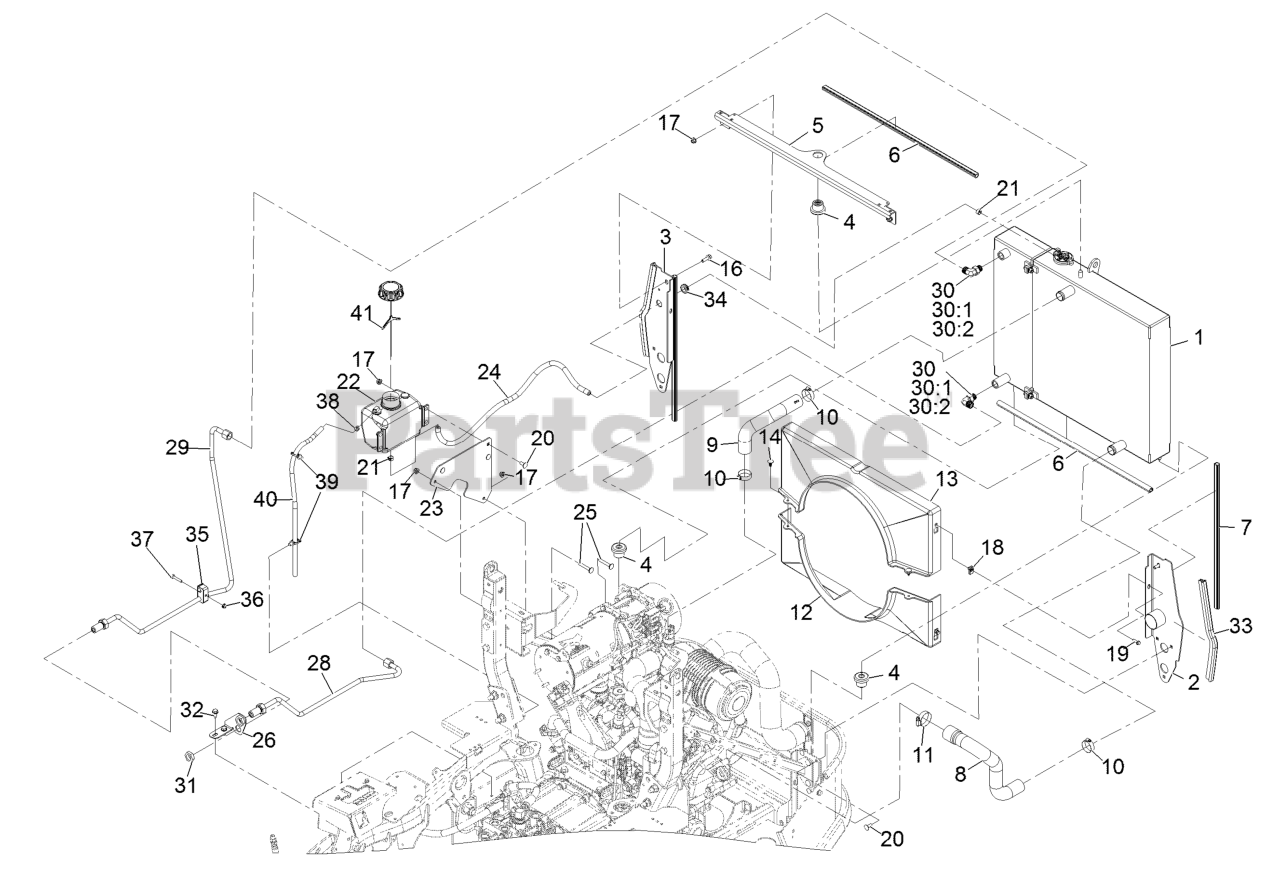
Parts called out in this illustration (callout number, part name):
1	Cooling ASM
2	Support-Radiator, LH
3	Support-Radiator, RH
4	Mount-Isolator
5	Bracket-Cooling, Top
6	Seal-Bulb
7	Seal-Bulb
8	Hose-Radiator, Lower
9	Hose-Radiator, Upper
10	Clamp-Hose
11	Clamp-Hose
12	Shroud-Bottom
13	Shroud-Top
14	Plug-Plastic
16	Screw-HH Flg 5/16-18 X 1
17	Nut-Nyloc 5/16-18 Flg
18	Nut-Retainer-Panel 1/4-20
19	Screw-Machine 1/4-20 X 3/4
20	Bolt-Carriage 5/16-18 X 3/4 Short Neckv
21	Clamp-Hose
22	Tank-Overflow, W/Cap
23	Bracket-Bottle
25	Bolt-Carriage 3/16-18 X 2
26	Bracket-Bulkhead
28	Hydraulic Tube ASM
29	Hydraulic Tube ASM
30	Fitting-Elbow, 90 DEG
30:1	O-Ring
30:2	O-Ring
31	Nut-Bulkhead
32	Screw-HWH 5/16-18 X 3/4 Tf
33	Seal-Bulb
34	Grommet
35	Clamp-Twin
36	Nut-Nyloc 1/4-20 Flg
37	Screw-HH 1/4-20 X 1 3/8
38	Clamp-Hose
39	Clip-Tie
40	Hose-Fuel
41	Cap-W/Tether, 2.25
